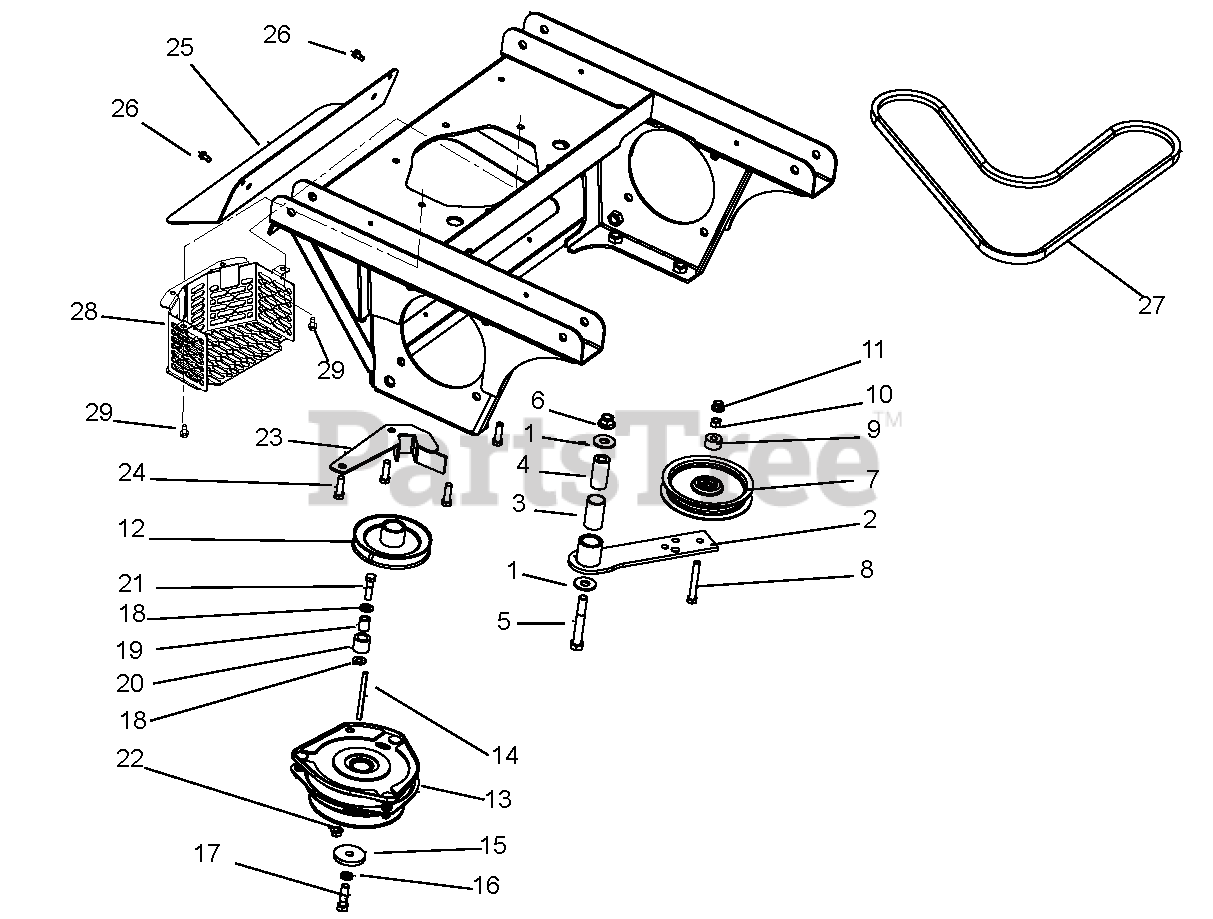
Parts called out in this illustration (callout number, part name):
1	Washer, Flat Steel.563 x 1.38 x .109YWZC
2	Weldment, Idler Arm Ground Drive
3	Bushing, 1.00 x 1.125 x 1.937
4	Bushing, Spacer .502 x .997 x 2.03 PM
5	Bolt, Hex .50-13 x 3.50 GR5 YWZC
6	Nut, Locking Nylon Flange .50-13 YWZC
7	Idler, Flat 5.00 x .38
8	Bolt, Hex .38-16 x 2.75 GR5 YWZC
9	Spacer .390 x 1.000 x .562
10	Nut, Locking Center .38-16 YWZC
11	Nut, Locking Nylon Flange .38-16 YWZC
12	Sheave, Engine 5.426 x 1.127
13	Clutch, Electric-OGURA GT3.5-VP01R
14	Key, Square .25 x 3.50 x .25 SAE
15	Washer, Flat Steel .469 x 2.00 x .25 YWZC
16	Washer, Lock .44 x .109 REG YWZC
17	Bolt, Hex .44-20 x 1.50 G5 YZ EP80
18	Washer, Flat Steel. 406 x .812 x .065 YWZ
19	Bushing, S.407 x .625 x .813 ST
20	Bumper, Rubber .62 x 1.0 x .88 LG
21	Bolt, Hex .38-16 x 1.50 GR5 YWZC
22	Nut, Locking Top Flange .38-16 YWZC
23	Weldment, Clutch Stop
24	Bolt, Hex .38-16 x 1.25 FTHG5 EP30YZ
25	Shield, Muffler Heat
26	Screw, Tap .25-20 x .50 Hex Washer Head TR YWZ
27	V-Belt, Cogged B-Raw Edge
28	Weldment, Clutch and Belt Guard
29	Screw, Tapping .38-16 x .50 Hex Washer Head
